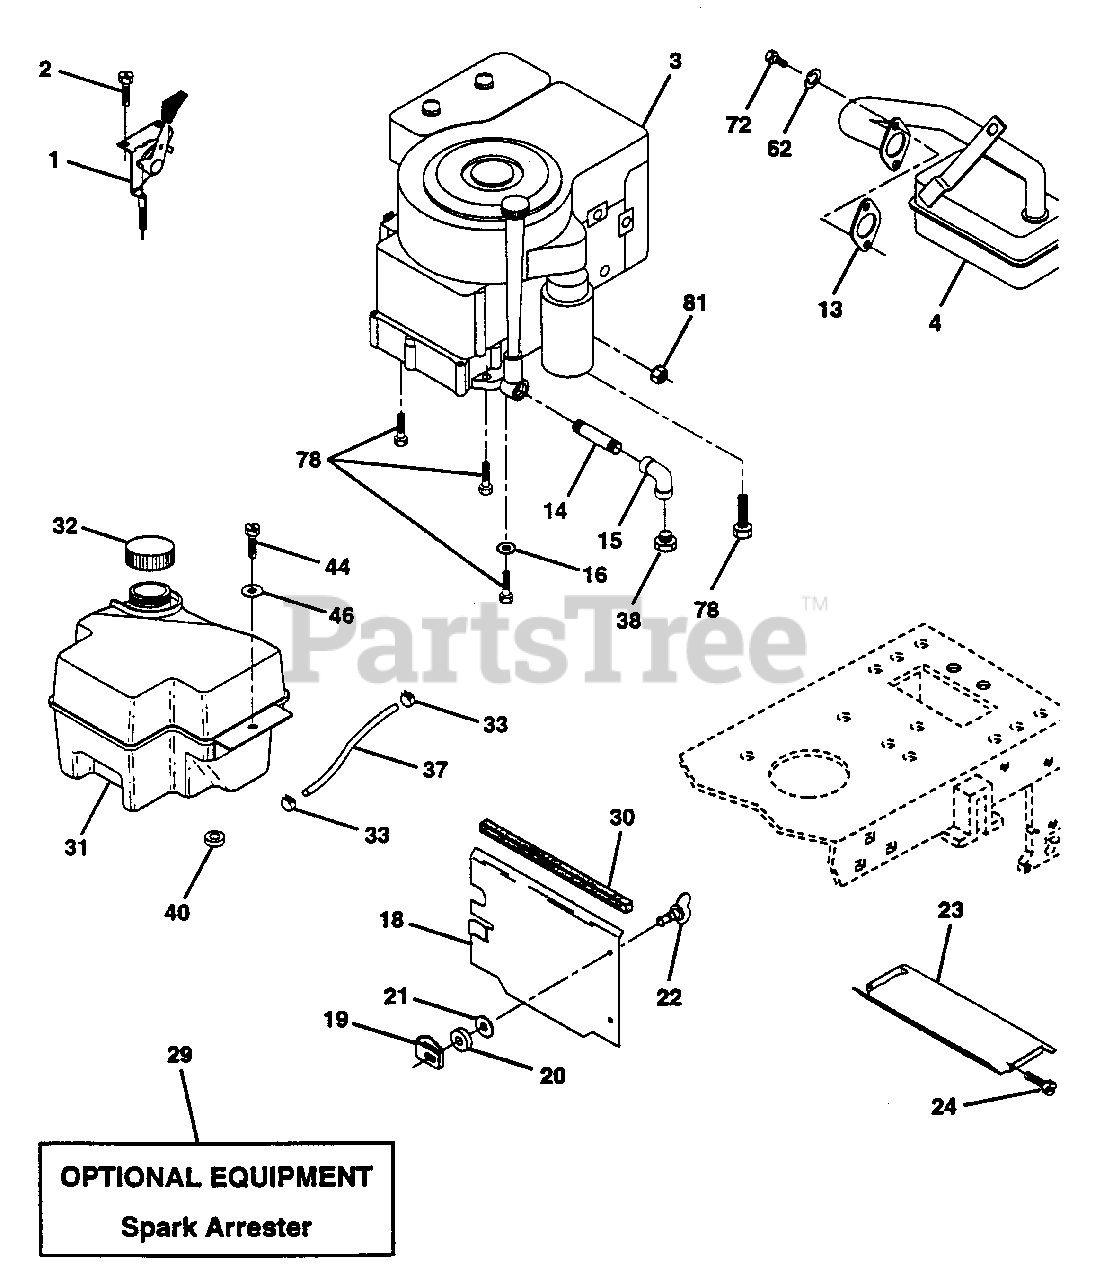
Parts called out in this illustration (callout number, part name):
1	Control Th/ch 23 5 LH Flag
2	Screw Hex Thd Cut 1/4-20x5/8 T
4	Muffler LT B&S 12/12.5/13HP
13	Gasket Eng 1 313 Id Tin Plated
14	Nipple Pipe 3/8 Npt X 3"
15	Elbow Std 90 Degree 3/8-18 Npt
16	Washer Lock Ext Tooth 3/8
18	Shield Heat Lt
19	Receptacle 1/4 turn
20	Retainer 1/4 turn
21	Washer 9/32 x 5/8 x 16 Ga.
22	Stud 1/4 turn
23	Shield Heat Browning LT/YT
24	Screw Tap Hex #10-24unc X 1/2
29	Kit Spark Arrestor (Flat Scrn)
30	Pinch Weld Hood Black
31	Tank Fuel Front 2 00
32	Cap Asm Fuel W/sym Vented
33	Clamp Hose Black
37	Line Fuel 20"
38	Plug Oil Drain
40	Bushing Snap Nyl Blk Fuel Line
44	Screw Hexwsh Thdrol 1/4-20x3/4
46	Washer 9/32 X 7/8 X 16 Ga
62	Washer Lock Hvy Hlcl Spr 5/16
72	Screw Hexhd Cap 5/16-18x 3/4
78	Screw Thdrol 3/8-16x1-1/4 TYTT
81	Nut Keps Hex 1/4-20 Unc
